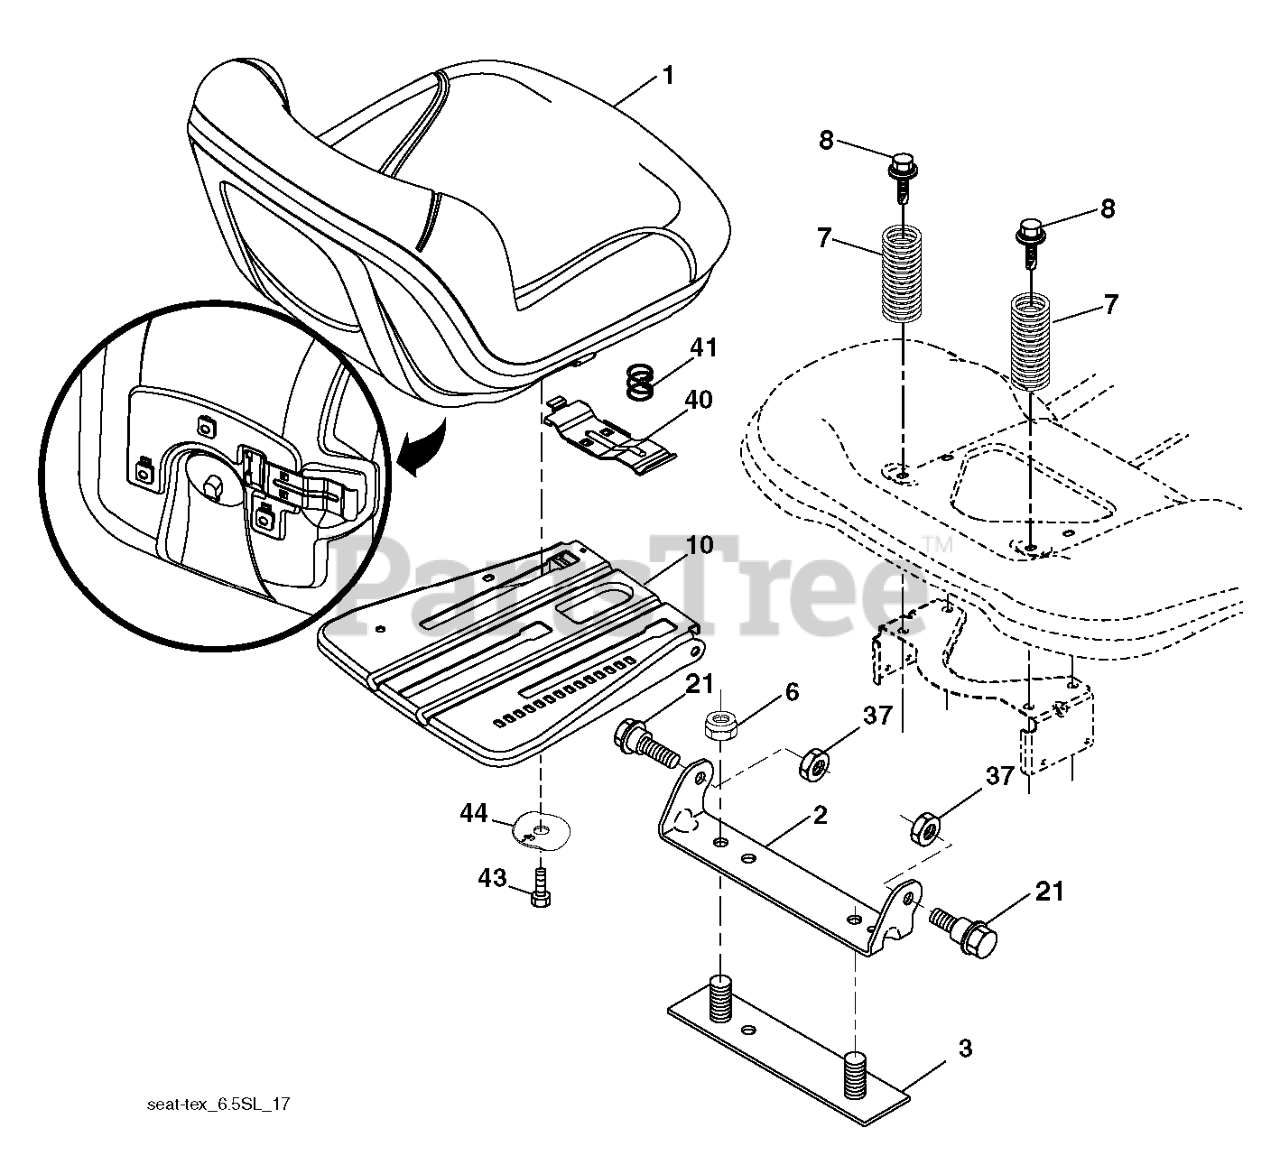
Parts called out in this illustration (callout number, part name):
1	SEAT.TH110.HUSQ.TEX.GREY
2	BRKT.PIVOT.FENDER
3	STRAP
6	NUT
7	SPRING.COMPRESS.SEAT.TAPERED
8	BOLT.5/16-18UNCX3/4 W/SEMS.BLK
10	PLATE.PNT.SEAT.SLIDE.3PT.EDIP
21	BOLT.5/16-18X5/8.SHOULDER
37	NUT.71038.31-18.HEX.NYLOCK
40	HANDLE.SLIDE.SEAT.TEX.BLACK
41	SPRING.LATCH.SEAT.TEX
44	WASHER.WINGED.3/8ID.1.5OD
